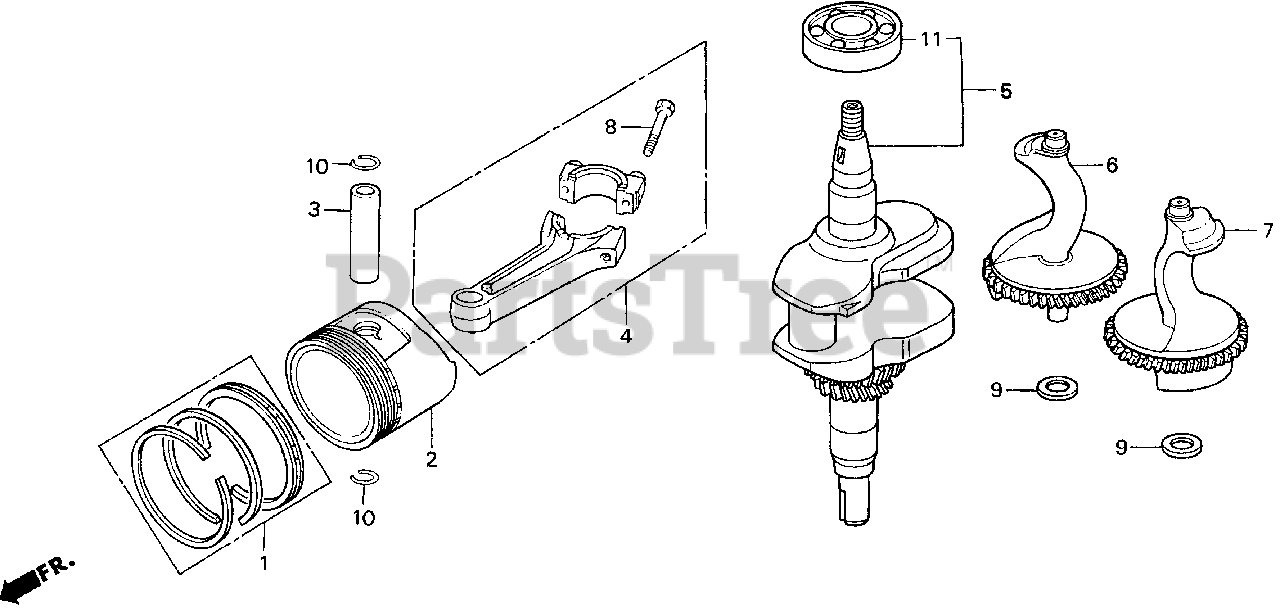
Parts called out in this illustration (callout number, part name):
1	RING SET, PISTON (STD)
1	RING SET, PISTON (OS 0.25)
1	RING SET, PISTON (OS 0.50)
1	RING SET, PISTON (0.75)
2	PISTON (STD)
2	PISTON (OS 0.25)
2	PISTON (OS 0.50)
2	PISTON (OS 0.75)
2	PISTON (0.75)
3	PIN, PISTON
4	ROD ASSY., CONNECTING
4	ROD ASSY., CONNECTING (US 0.25)
4	ROD ASSY., CONNECTING (STD)
5	CRANKSHAFT (NOT AVAILABLE)
5	CRANKSHAFT
6	WEIGHT A, BALANCER
7	WEIGHT B, BALANCER
8	BOLT, CONNECTING ROD
9	WASHER, THRUST (14MM)
10	CLIP, PISTON PIN (20MM)
11	BEARING, RADIAL BALL (6207)
